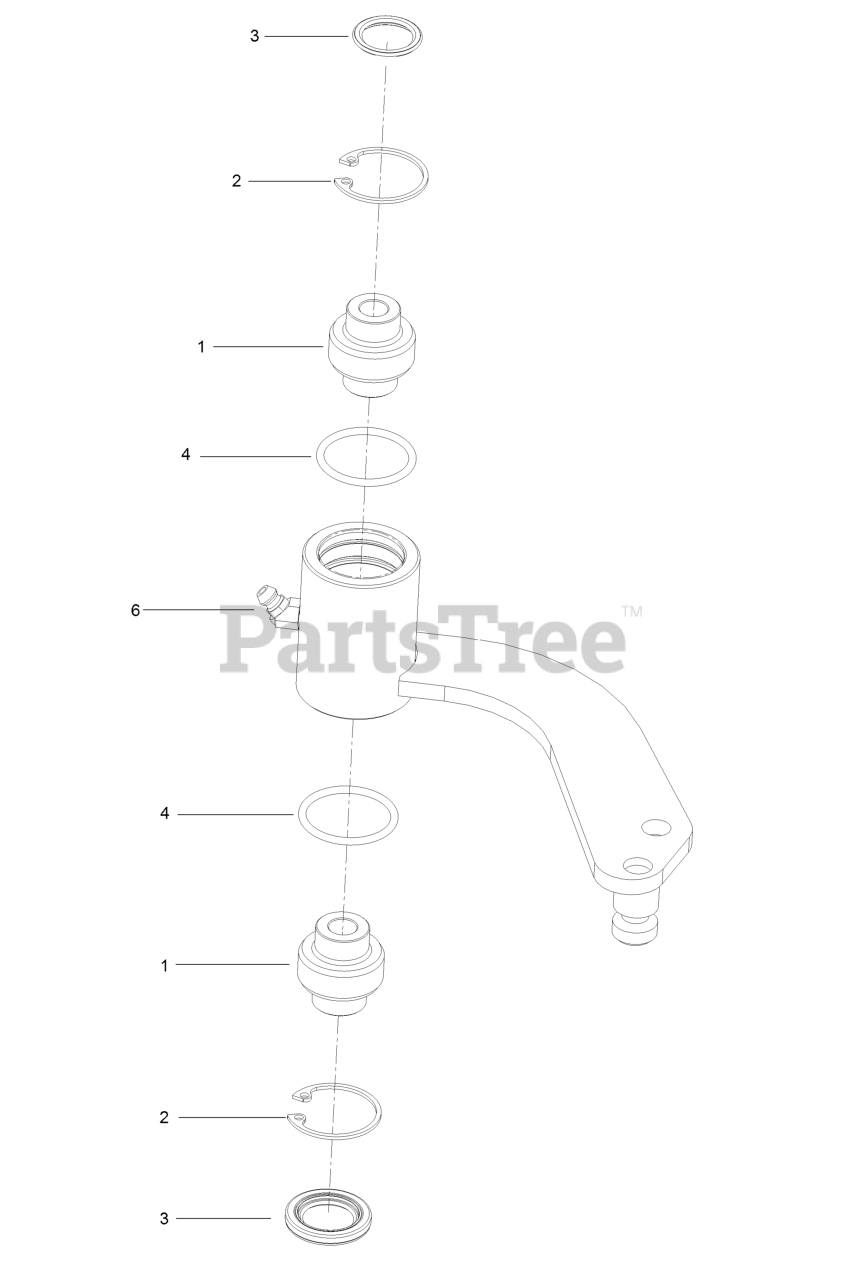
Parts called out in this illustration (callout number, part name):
1	Bearing-Spherical
2	Ring-Snap
3	Seal-Lip, Single
6	Fitting-Lube, 45 DEG
